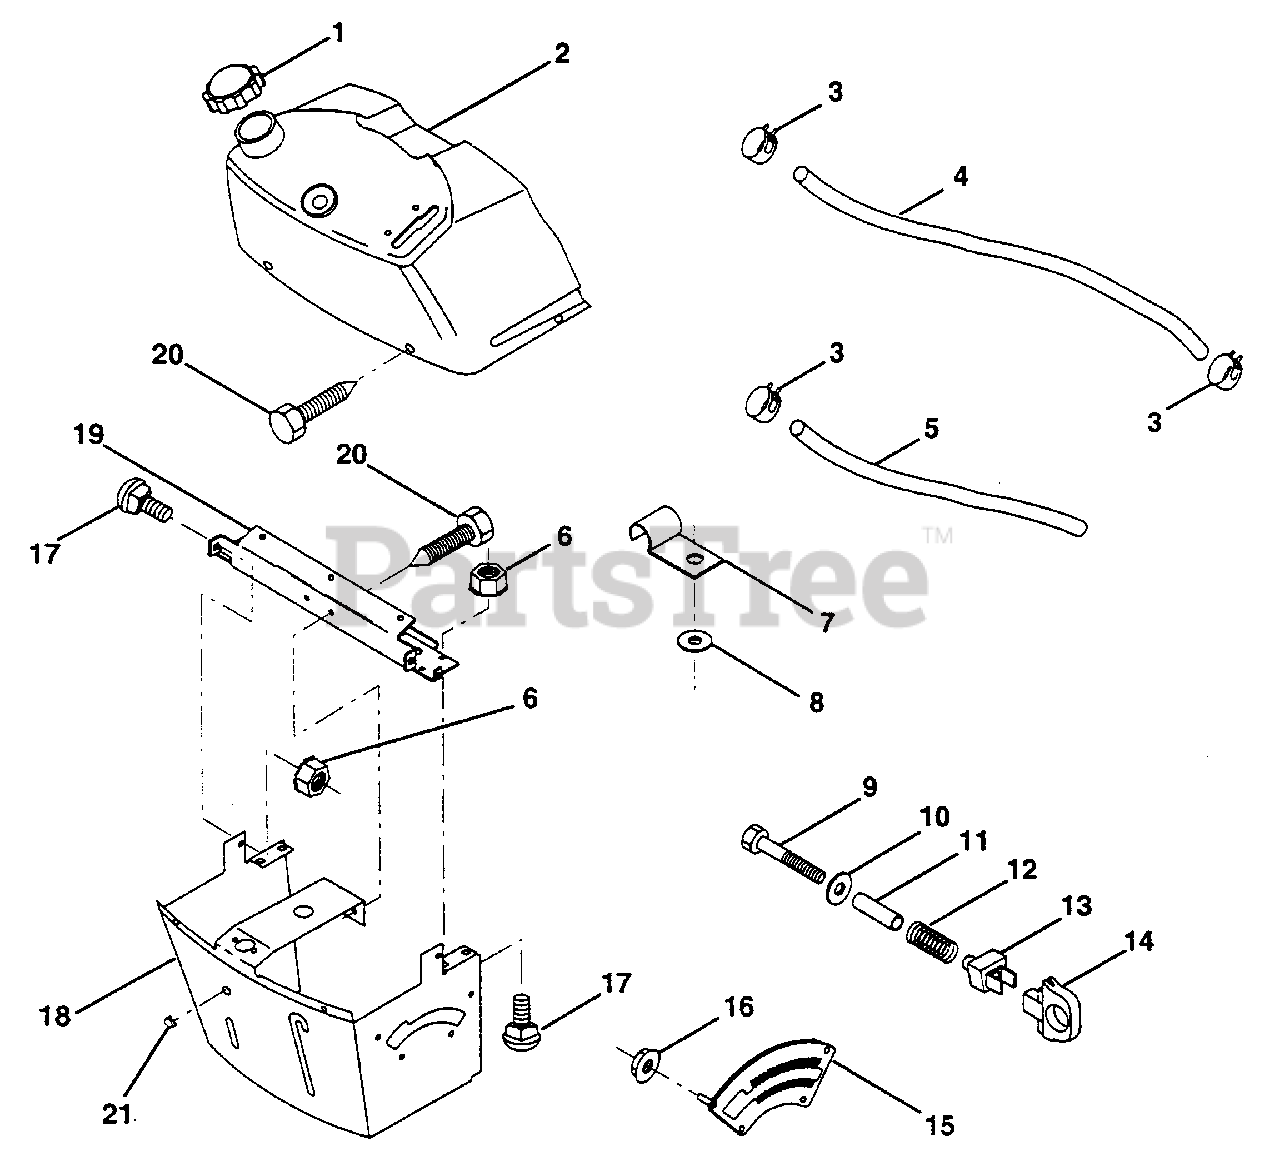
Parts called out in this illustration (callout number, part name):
1	Cap, Fuel (AYP part number)
2	Assembly, Dash & Fuel Tank (AYP part number)
3	Clamp, Hose (AYP part number)
4	Line, Fuel (AYP part number)
5	Line, Fuel (AYP part number)
6	Nut, Hex, Keps 1/4-20 (AYP part number)
7	Clip, Fuel Line (AYP part number)
8	Washer 9/32 x 3/4 x 16 Ga. (AYP part number)
9	Bolt, Hex, Fin 1/4-20 x 1-3/4 (AYP part number)
10	Washer 11/32 x 11/16 x 16 Ga. (AYP part number)
11	Spacer, Split (AYP part number)
12	Spring (AYP part number)
13	Clip, Height Adjustment (AYP part number)
14	Knob, Height Stop (AYP part number)
15	Adjustment, Quadrant Height (AYP part number)
16	Nut, Self-Threading 3/16-18 (AYP part number)
17	Bolt, Carriage 1/4-20 x 1/2 Gr. 5 (AYP part number)
18	Support Assembly, Dash (AYP part number)
19	Brace, Cross (AYP part number)
20	Screw, Self-Tapping 1/4-20 x 1/2
21	Plug, Dome Black (AYP part number)
